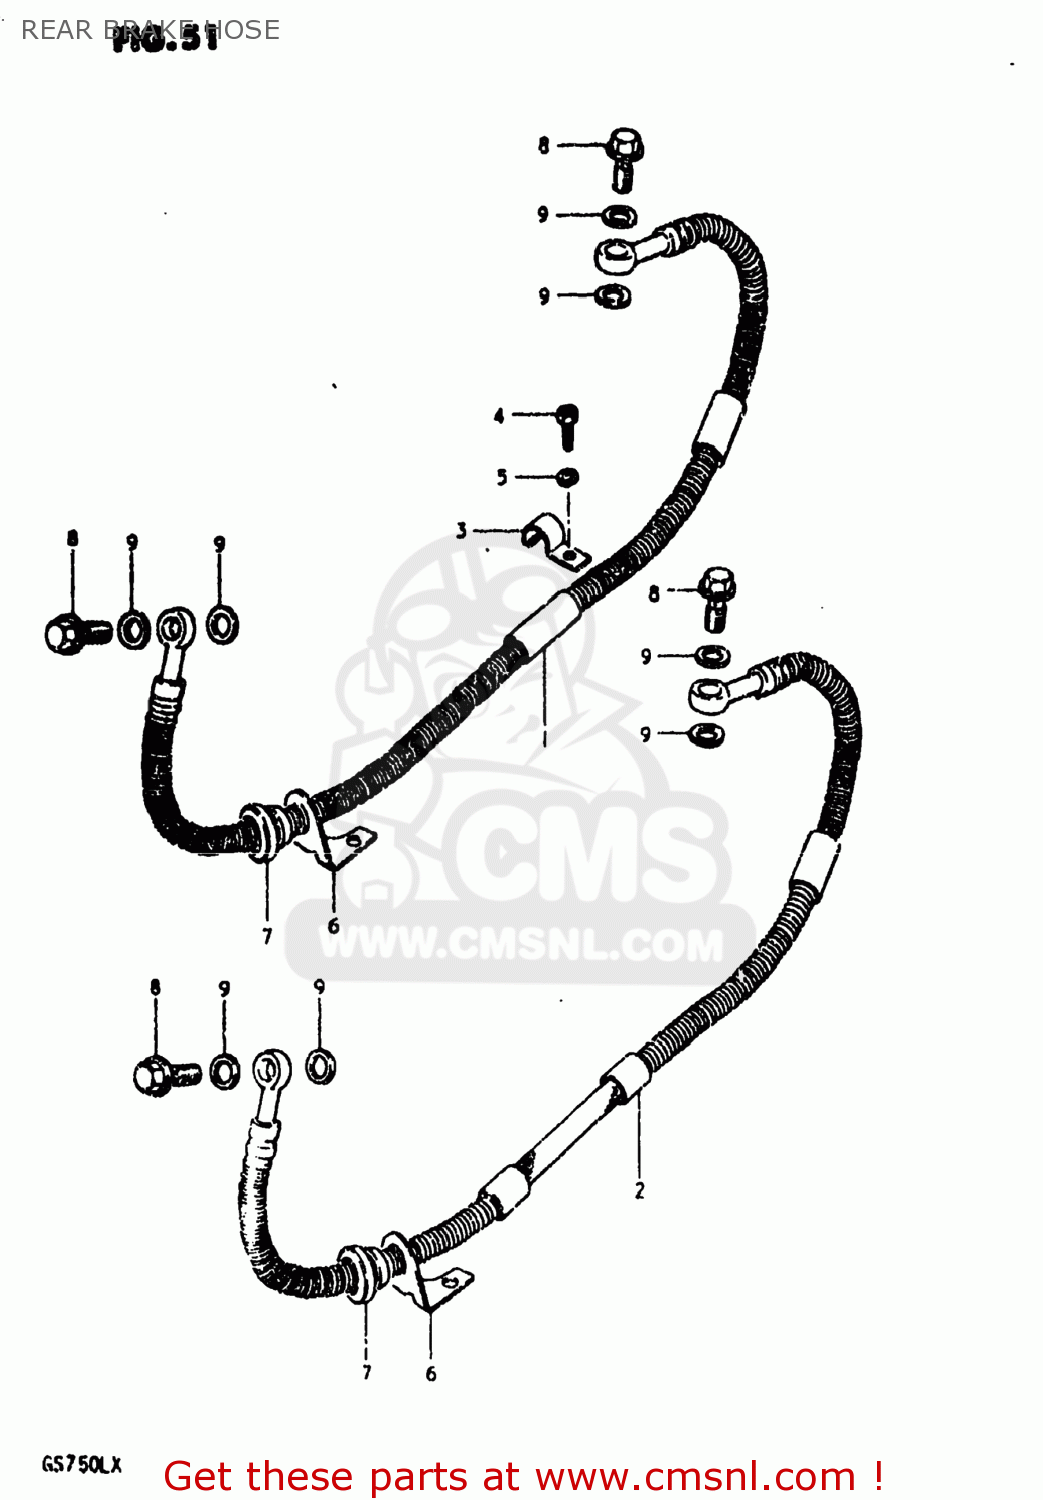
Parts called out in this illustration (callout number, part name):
1	HOSE,REAR BRAKE
2	HOSE,REAR BRAKE
3	CLAMP,REAR BRAKE HOSE
4	SCREW(6X8)
5	LOCK WASHER
6	GUIDE,BRAKE HOSE
7	GROMMET,BRAKE HOSE GUIDE
8	BOLT,UNION
9	WASHER
